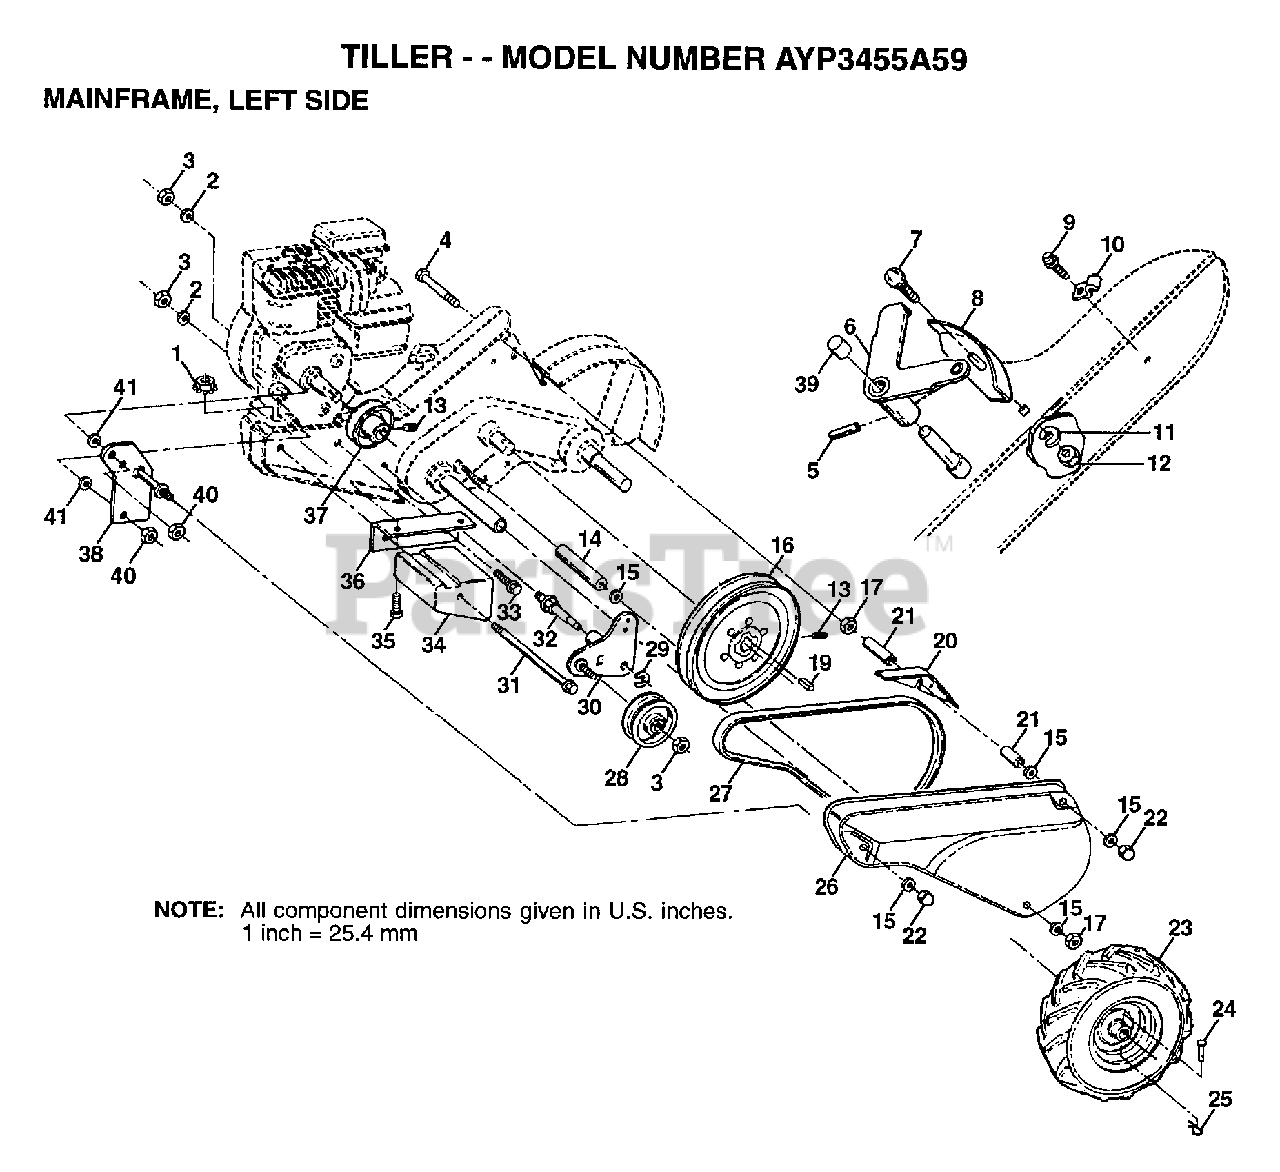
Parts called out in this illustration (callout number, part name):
2	LOCKWASHER
3	NUT.HEX.3/8-16UNC
4	BOLT TI
6	LEVER ASM CRT
7	BOLT
8	PANEL TI
10	CONDIUT CLIP T
11	LOCKWASHER
13	SET SCREW
14	SPACER
15	WASHER
16	"SHEAVE 10"" CRT"
17	NUT.HEX.5/16-18
18	SPACER CRT
19	KEY T
20	GUARD CRT
21	SPLIT SPACER
22	NUT TI
23	TIRE TI
24	RIVET.DRILL.1.75
25	RETAINER M
26	GUARD.BELT.SILKSC
27	BELT-V
28	PULLEY-IDLER TI
29	KLIP RING
31	BOLT CRT
32	SHIFT ARM CRT
33	BOLT
34	COUNTERWEIGHT CRT
35	BOLT.HEX.5/16-1.5
36	BRACKET LH CRT
37	ENGINE PULLEY
39	CAP PLUNGER BLACK
40	NUT
41	WASHER
